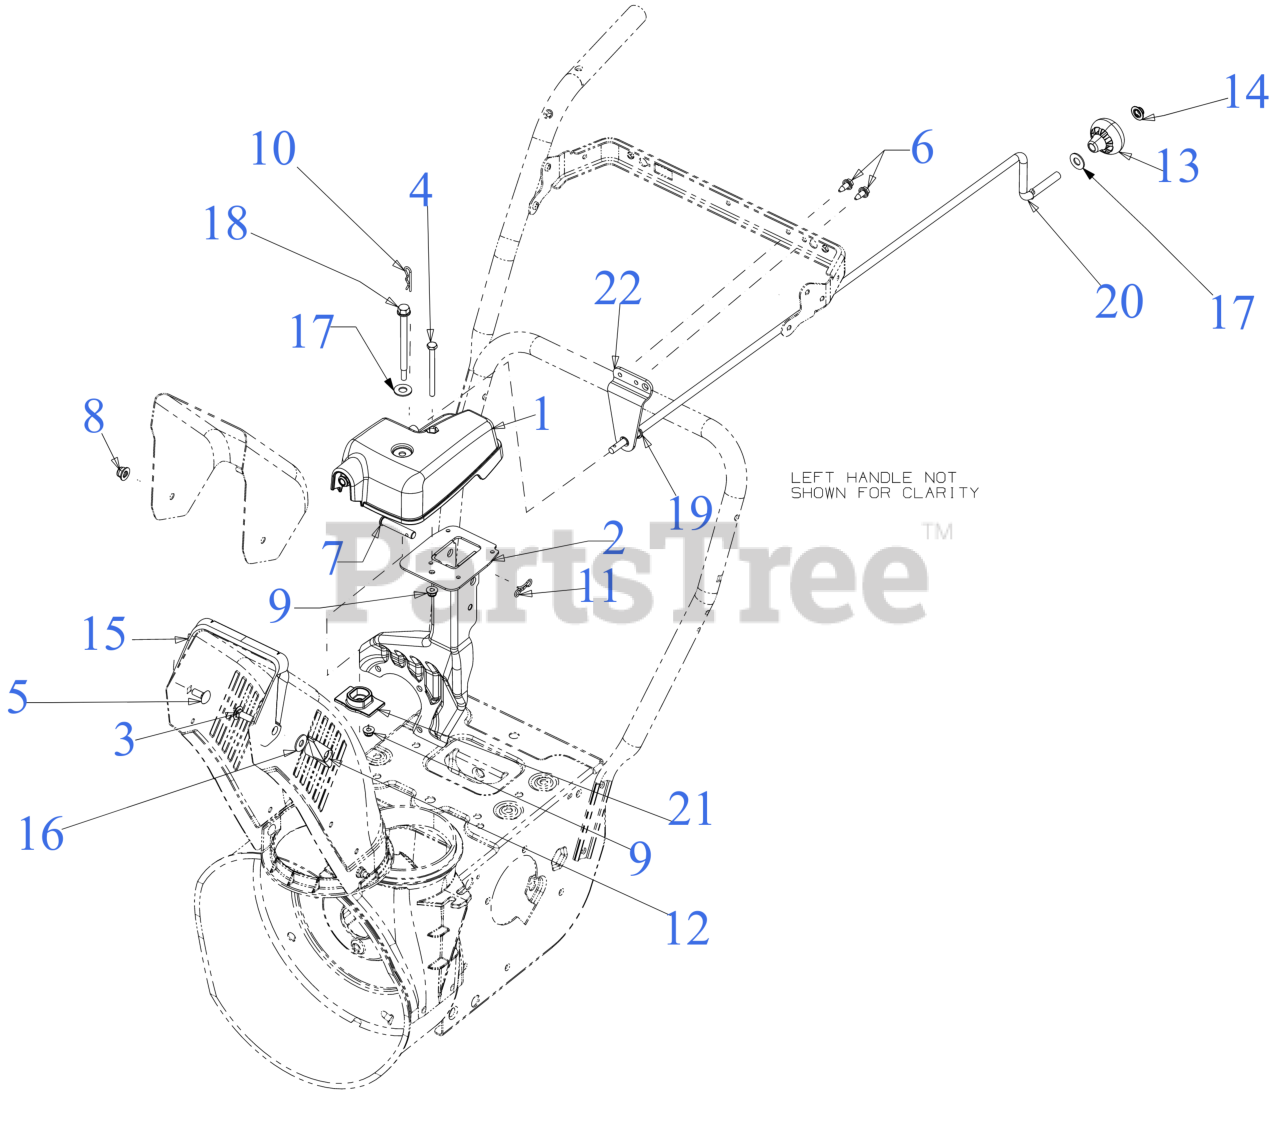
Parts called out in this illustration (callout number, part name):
1	2-WAY CHUTE ROTATE GEARBOX
2	CHUTE SUPPORT ASSEMBLY
3	CARRIAGE BOLT 5/16-18 x 1.00
4	SCREW 1/4-20 x 3.0 GR5
5	CARRIAGE BOLT 5/16-18 x .75
6	SCREW 1/4-20X.625
7	CLEVIS PIN 3/8 x 1.87
8	FLANGE LOCK NUT 5/16-18
9	FLANGE LOCK NUT
10	INTERNAL COTTER PIN
11	BOW TIE COTTER PIN 1/4-5/16
12	WING KNOB NUT
13	SHIFT KNOB
14	PUSH NUT
15	UPPER CHUTE ADAPTER
16	FLAT WASHER
17	FLAT WASHER
18	SHOULDER SCREW
19	BUSHING .380 ID
20	CHUTE CRANK .375 DIA x 31"
21	HELICAL GEAR CHUTE ADAPTER
22	ROD SUPPORT BRACKET
